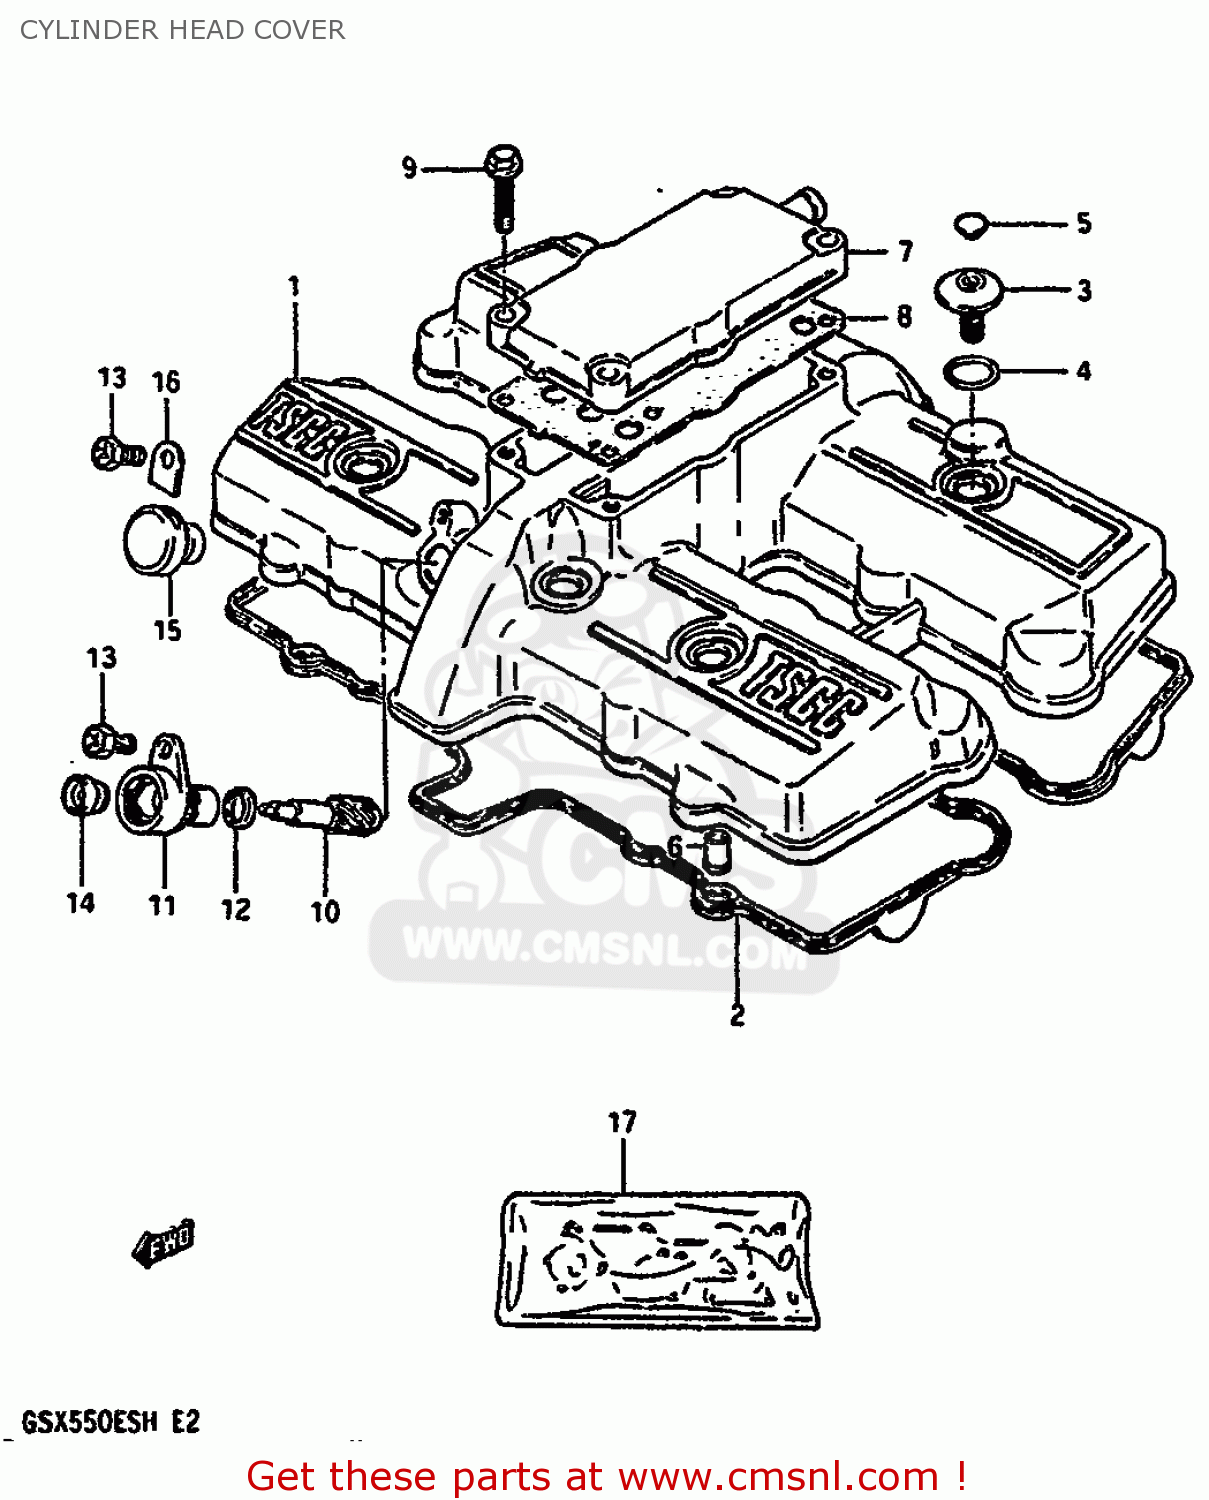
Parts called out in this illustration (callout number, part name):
1	COVER,CYLINDER HEAD
2	GASKET,CYL HEAD COVER (NAS)
3	BOLT(7X5.5)
4	O RING(D:1.9,ID:14.5)
5	CAP(OD:10)
6	PIN
7	COVER,BREATHER
8	GASKET (MCA)
9	BOLT
10	GEAR,TACHOMETER DRIVEN
11	SLEEVE,TACHOMETER DRIVE GEAR
12	SEAL,TACHOMETER DRIVEN
13	SCREW(5X12)
14	SEAL,OIL(5X12X8)
15	PLUG,TACH GEAR SLEEVE HOLE
16	PLATE,TACH DRIVE GEAR SLEEVE
17	GASKET SET (MCA)
